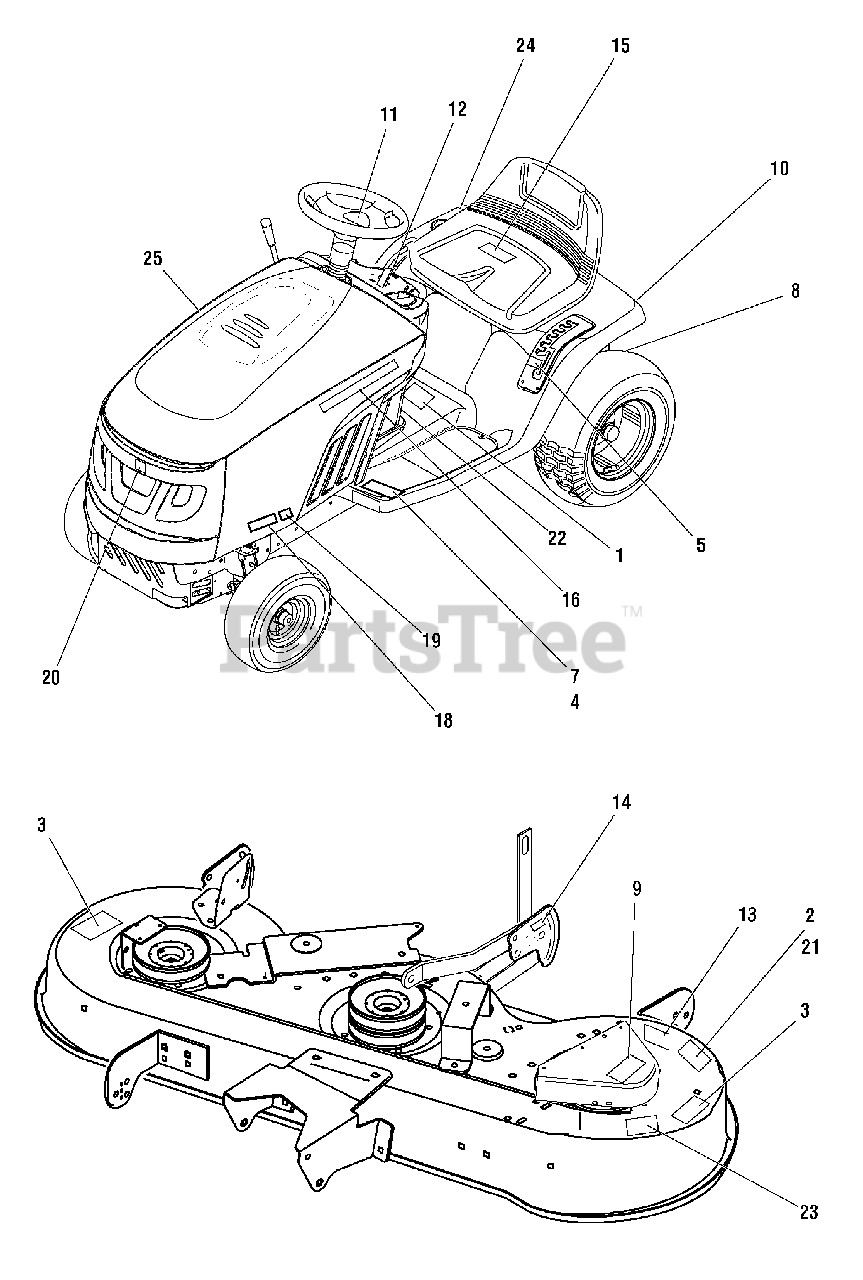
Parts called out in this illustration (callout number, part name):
1	DECAL, Umber
2	DECAL, No Step
3	DECAL, Danger, Do Not Operate Without Deflector
4	DECAL, Drive Pedal
5	DECAL, Height of Cut
7	DECAL, Belt/Clutch
8	DECAL, Weight Limitation
9	DECAL, Cut, 46
10	DECAL, Allis Chalmers, Rear
11	DECAL, Steering Wheel
12	DECAL, Manual PTO
13	DECAL, Gauge Wheel Instruction, Eng/FC
14	DECAL, Deck Level, ENG/FC
15	DECAL, Auto Drive Dump Valve
16	DECAL, Stripe, Allis Chalmers, Strip, With Logo
18	DECAL, Model, AC130 23HP
19	DECAL, Logo, Allis Chalmers LT125
20	DECAL, Logo
21	DECAL, No Step, FC
22	DECAL, Danger, FC
23	DECAL, Cut Hand/ Foot, FC
24	DECAL, Deck Level Position, Eng/FC
